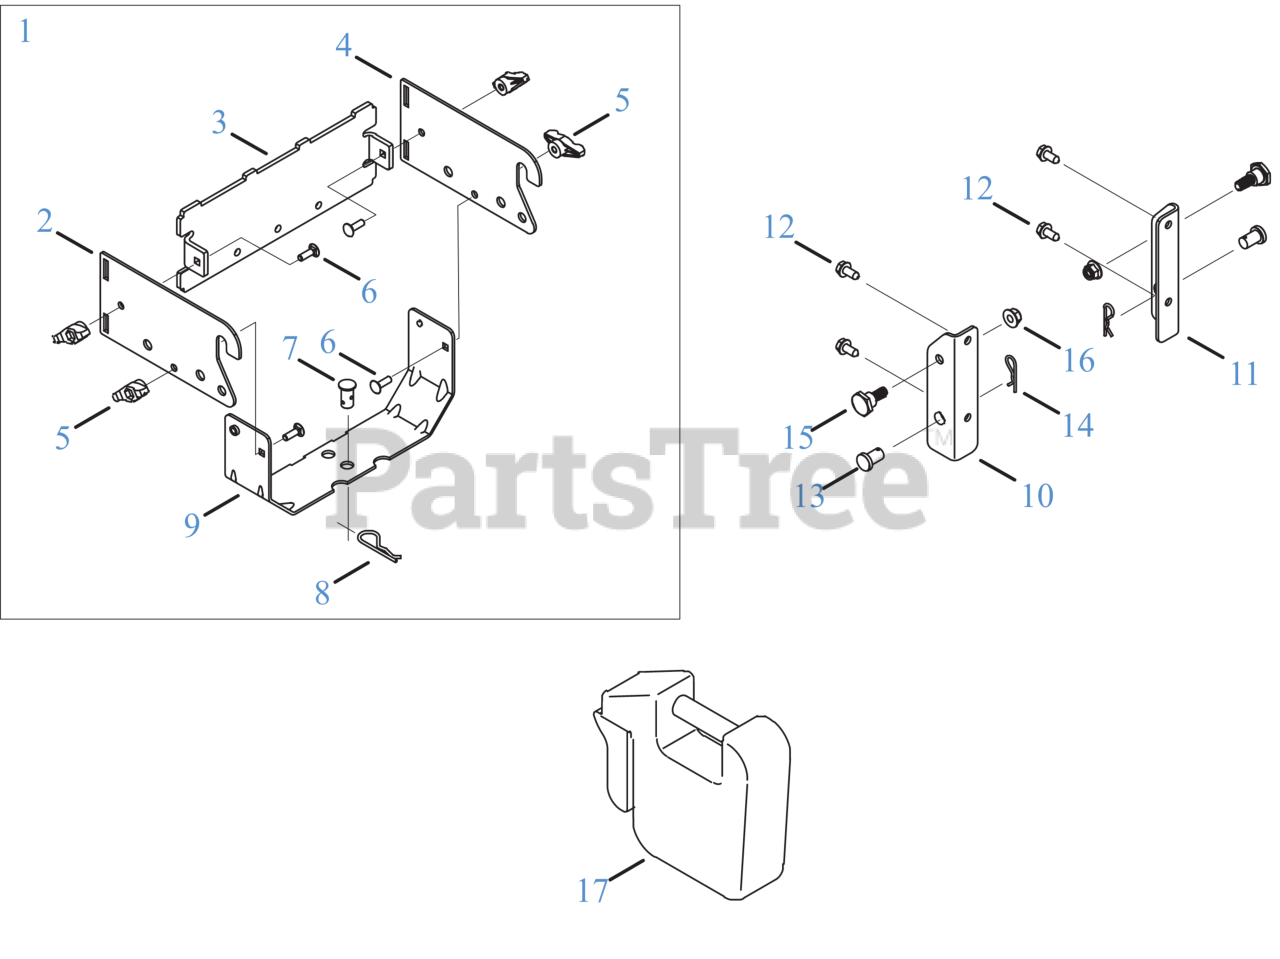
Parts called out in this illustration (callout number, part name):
1	HITCH BRACKET ASSEMBLY
2	Hitch Bracket, RH
3	Rear Attachment Bracket
4	Hitch Bracket, LH
5	WING KNOB 5/16-18
6	CARRIAGE BOLT 5/16-18 x 1.00
7	CLEVIS PIN .62
8	INTERNAL COTTER PIN
9	GRASSBAG HITCH BRACKET
12	SCREW 5/16-18 x .750
13	LIFT BRACKET PIN
14	INTERNAL COTTER PIN
15	SHOULDER SCREW .625 x .412
17	Genuine Factory Parts WEIGHT - SUITCASE 42LB PLASTIC
